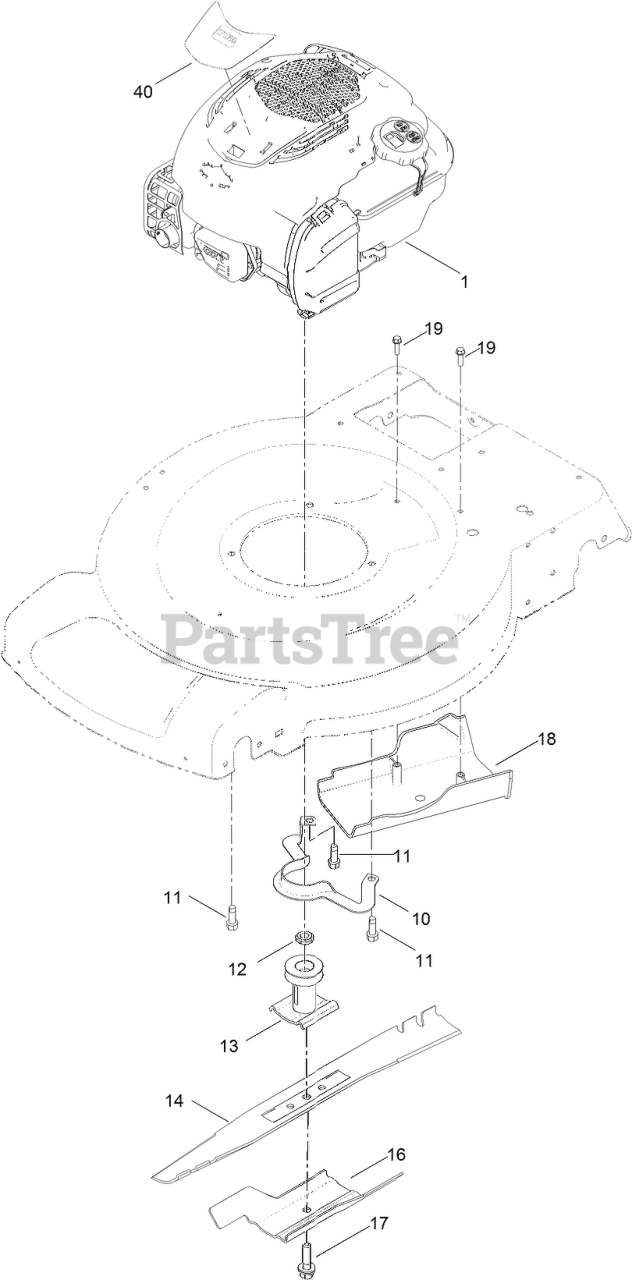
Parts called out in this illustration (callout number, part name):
10	Guide-Belt
11	SCREW-TAPTITE
12	Spacer-Driver
13	DRIVER-BLADE
16	Accelerator-Blade
17	BOLT-BLADE
18	COVER-BELT
19	SCREW-HWH
40	DECAL-SHROUD
